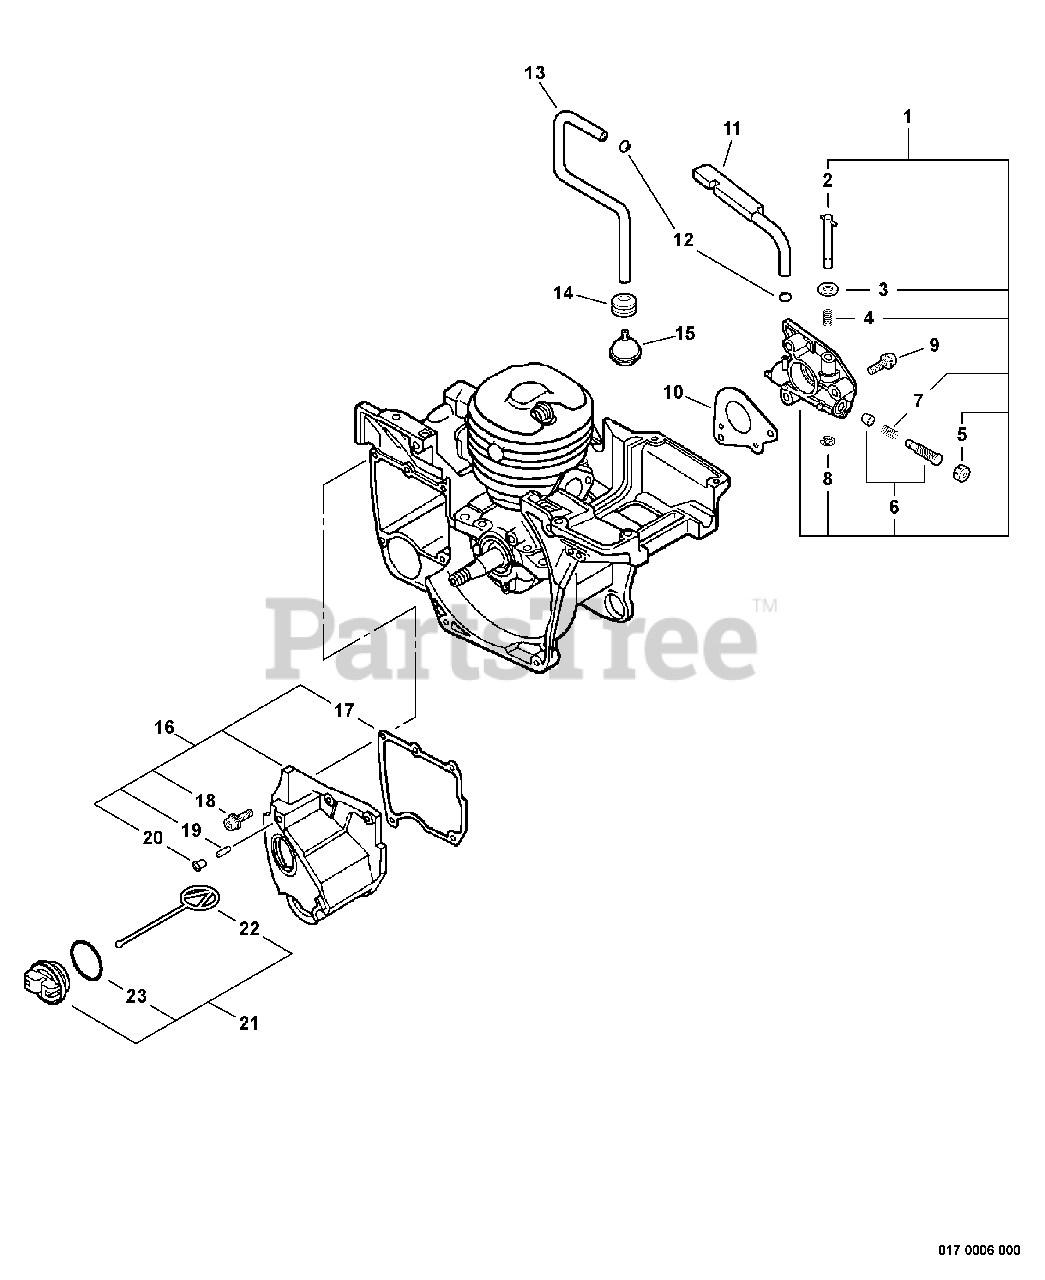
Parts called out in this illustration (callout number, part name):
1	AUTO-OILER ASSY
2	SCREW, ADJUSTER
5	CAP, OIL PUMP
6	PLUNGER ASSY
9	SCREW 4×16
10	PLATE, SEAL
11	PIPE, OIL OUTLET
12	CLIP Ø6.5 MM
13	PIPE, OIL
15	FILTER, OIL
16	TANK, OIL
17	GASKET, OIL TANK
18	BOLT 4×16
19	VENT ASSY
20	COLLAR 5.5×6.65×5
21	CAP ASSY, OIL
22	CONNECTOR, CAP L= 60 MM
